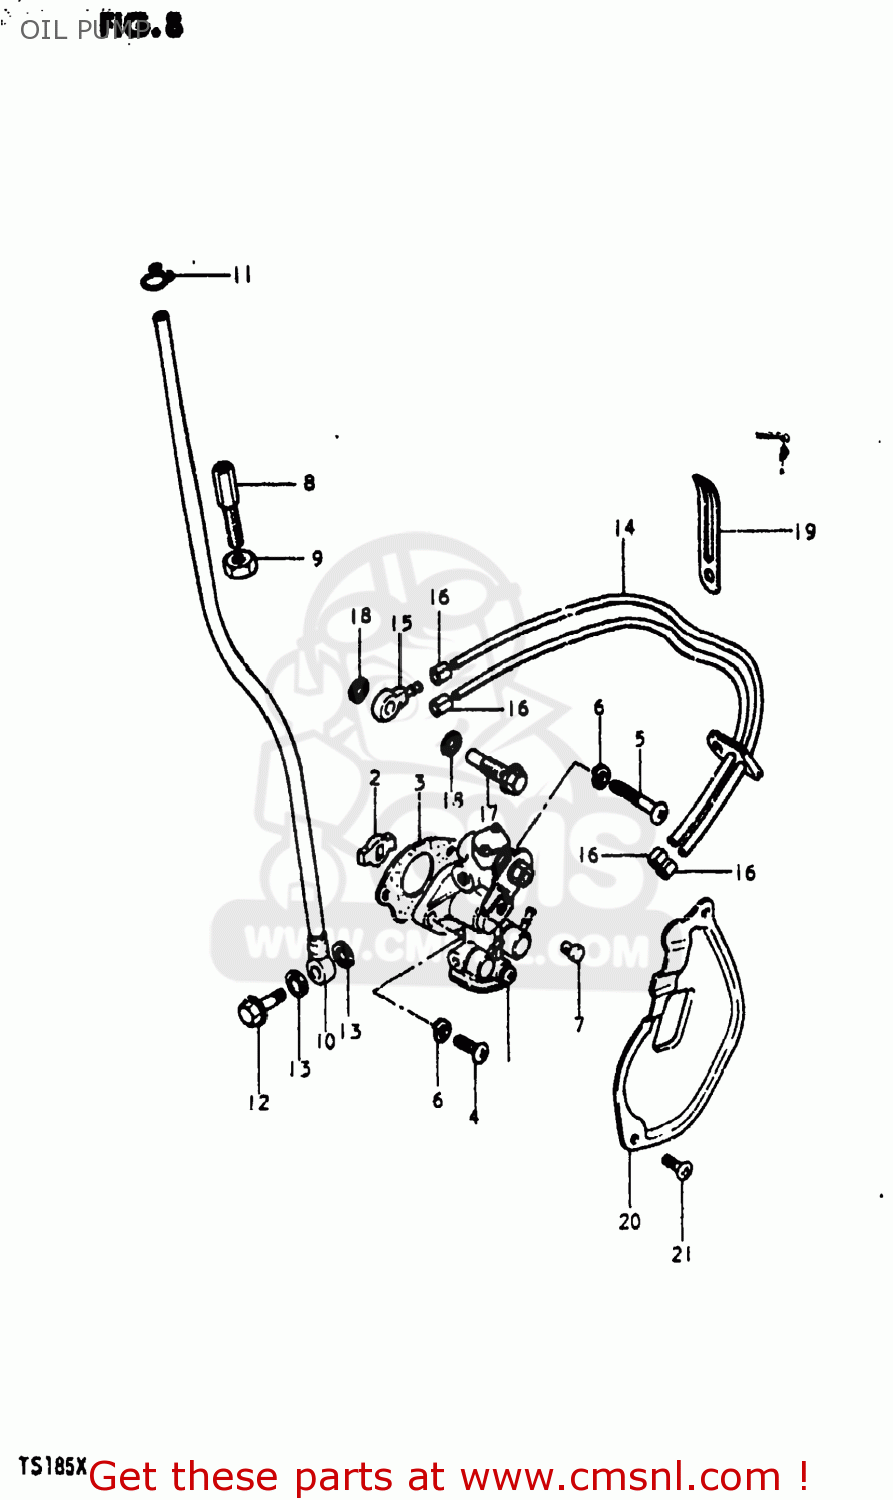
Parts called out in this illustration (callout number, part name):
1	PUMP ASSEMBLY,OIL
2	PIECE,OIL PUMP DRIVE
3	GASKET,OIL PUMP (NAS)
4	SCREW
5	SCREW
6	LOCK WASHER
7	TERMINAL,CABLE
8	BOLT
9	NUT
10	HOSE,OIL NO.1
11	CLIP
12	UNION BOLT
13	GASKET(6.2X11X1).2 (NAS)
14	HOSE,OIL NO.2
15	UNION
16	CLIP
17	UNION
18	GASKET(6.2X11X1).2 (NAS)
19	CLAMP L:35
20	CAP,OIL PUMP INSPECTION
21	SCREW
